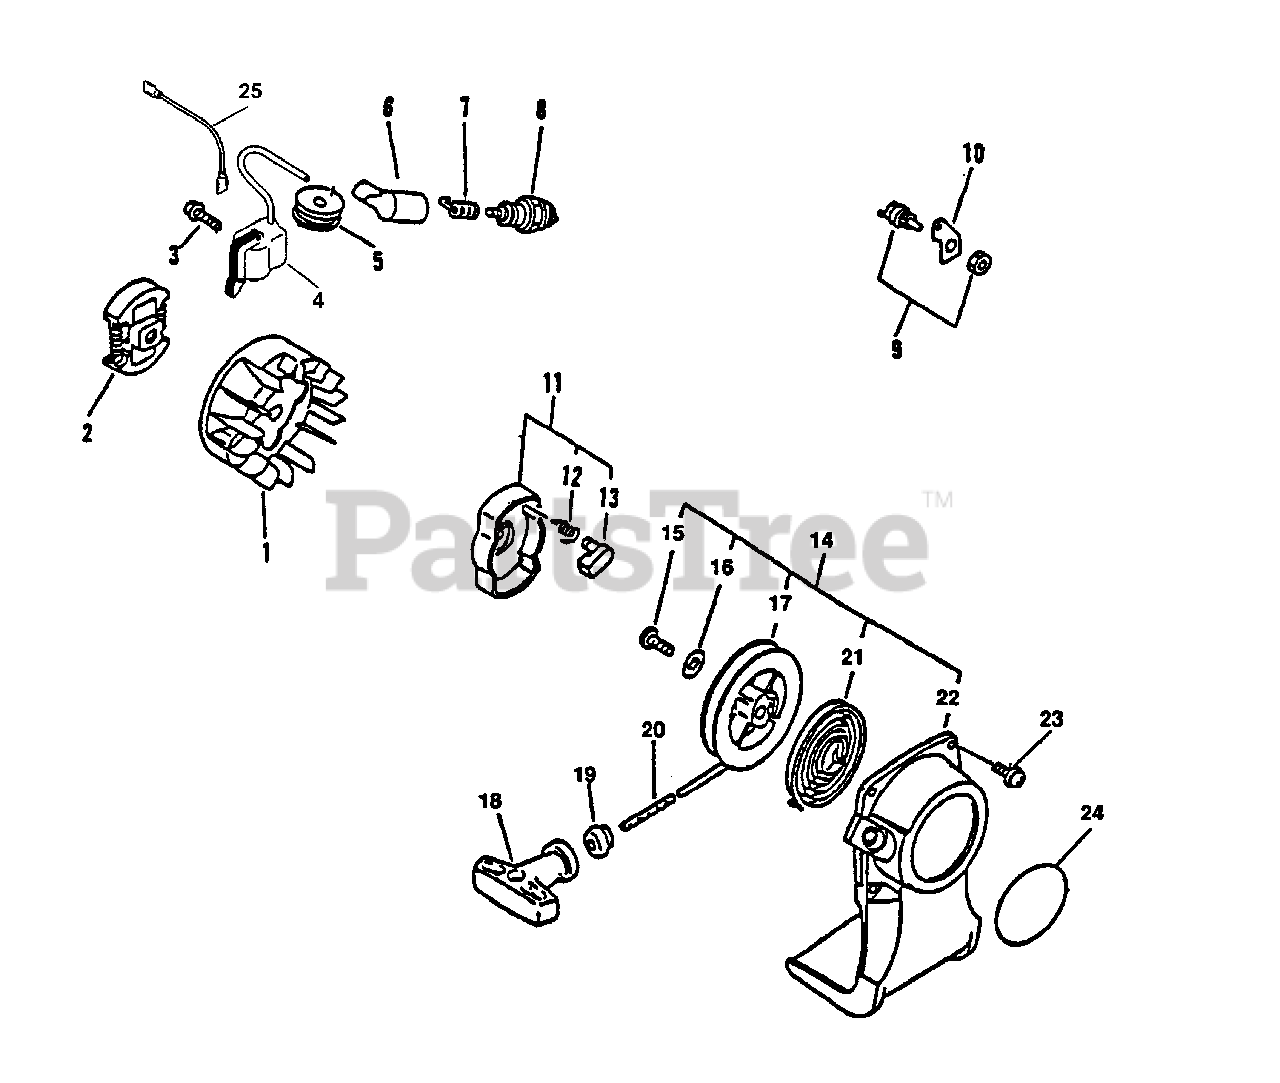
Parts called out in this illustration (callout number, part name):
1	FLYWHEEL
2	CLUTCH ASSY
3	SCREW - 4X22
4	COIL, IGNITION
5	GROMMET
6	CAP, SPARK PLUG
7	TERMINAL, SPARK PLUG CAP
8	SPARK PLUG -- BPM-7A
8	SPARK PLUG -- BPMR-7A
9	IGNITION SWITCH ASSY
10	BRACKET, SWITCH
11	STARTER PAWL ASSY
12	SPRING, RETURN
13	PAWL, STARTER - BLACK
14	STARTER ASSY
16	WASHER
17	REEL, ROPE
18	GRIP, STARTER
19	GUIDE, ROPE
20	ROPE, STARTER - 3X890
21	SPRING, REWIND
22	CASE, STARTER - BLUE
23	SCREW - 4X16
24	LABEL - ECHO
25	LEAD - GROUND
